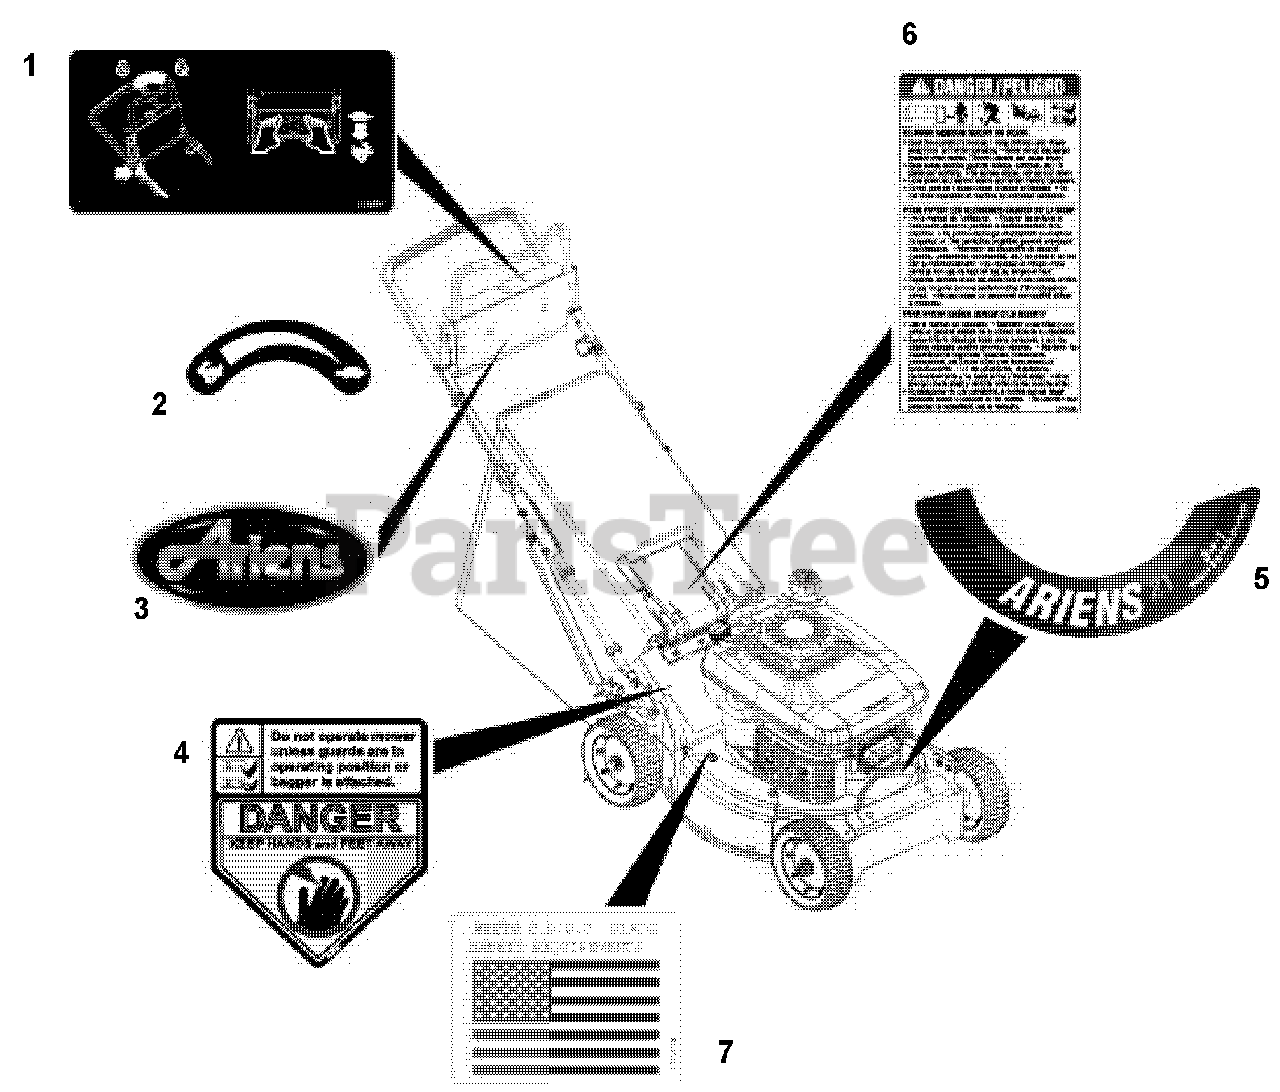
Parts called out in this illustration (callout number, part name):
1	DECAL,CONTROL
2	DECAL, TURTLE & RABBIT
3	DECAL-ARIENS JEWEL
4	DECAL, CPSC DANGER
5	DECAL-PRO21 XD ARIENS
6	DECAL, BILINGUAL DANGER
7	DECAL, CPSC/USA FLAG
